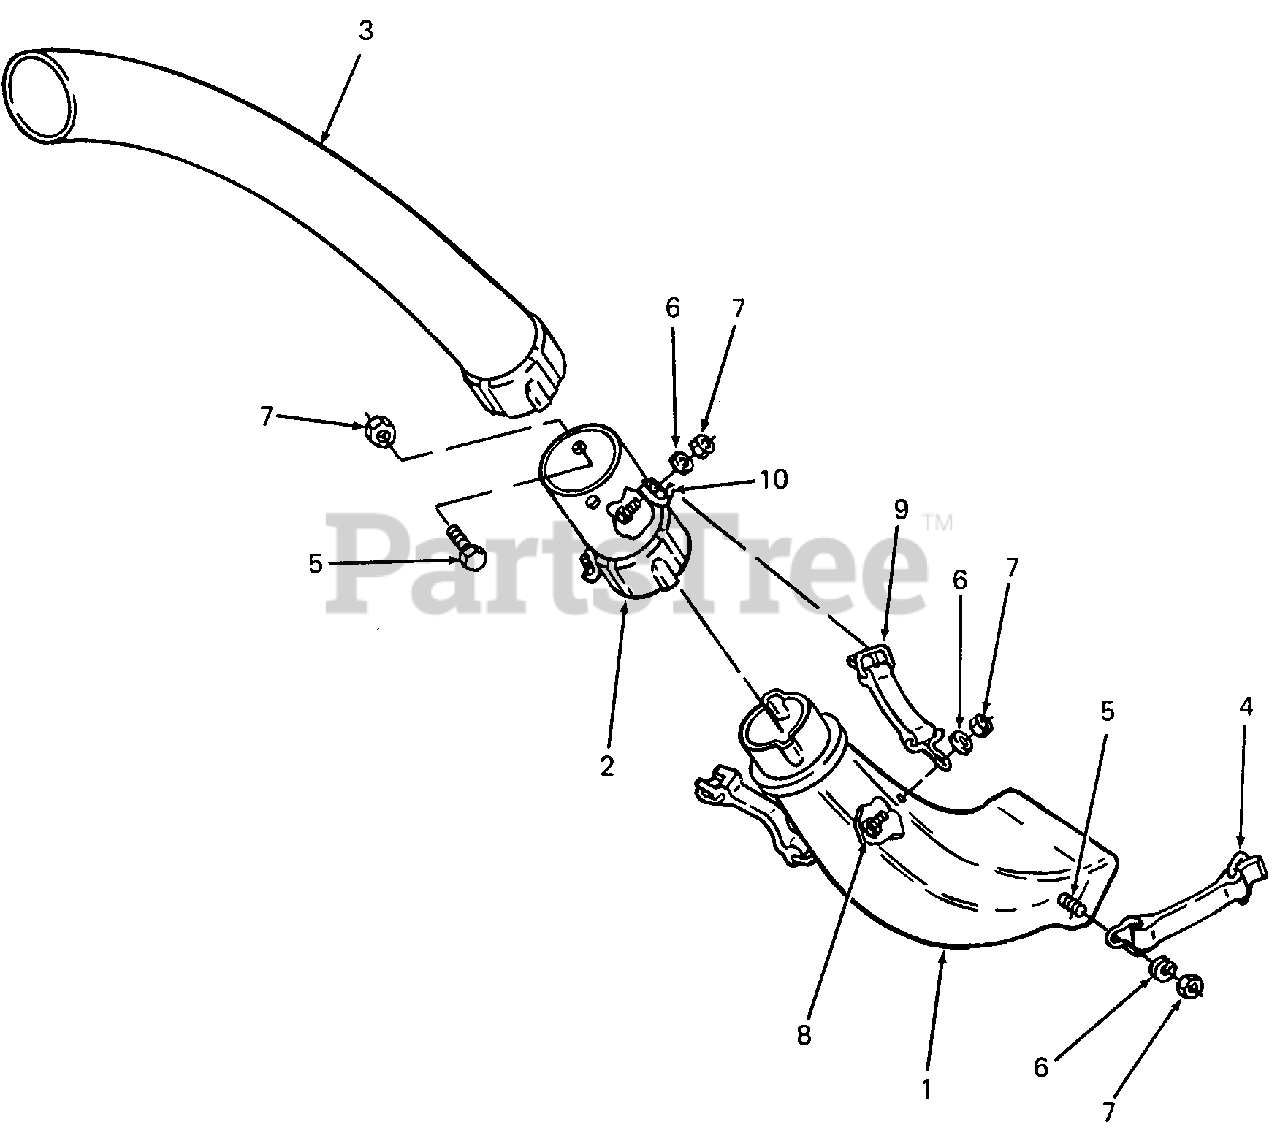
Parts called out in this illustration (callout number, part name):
1	Chute, Discharge
2	Extension, Tube
3	Elbow, Catcher
4	Strap Assy, Chute Retainer
5	Screw, Hex, 1/4-20 X .62 Lg
6	Washer, Spring, .265 X .562
7	Nut, Hex Insert Lock, 1/4-20
8	Screw, Hex Cap, 1/4-20 X .50 Lg
9	Strap Assy, Retainer
10	Hook Bracket, Retainer
